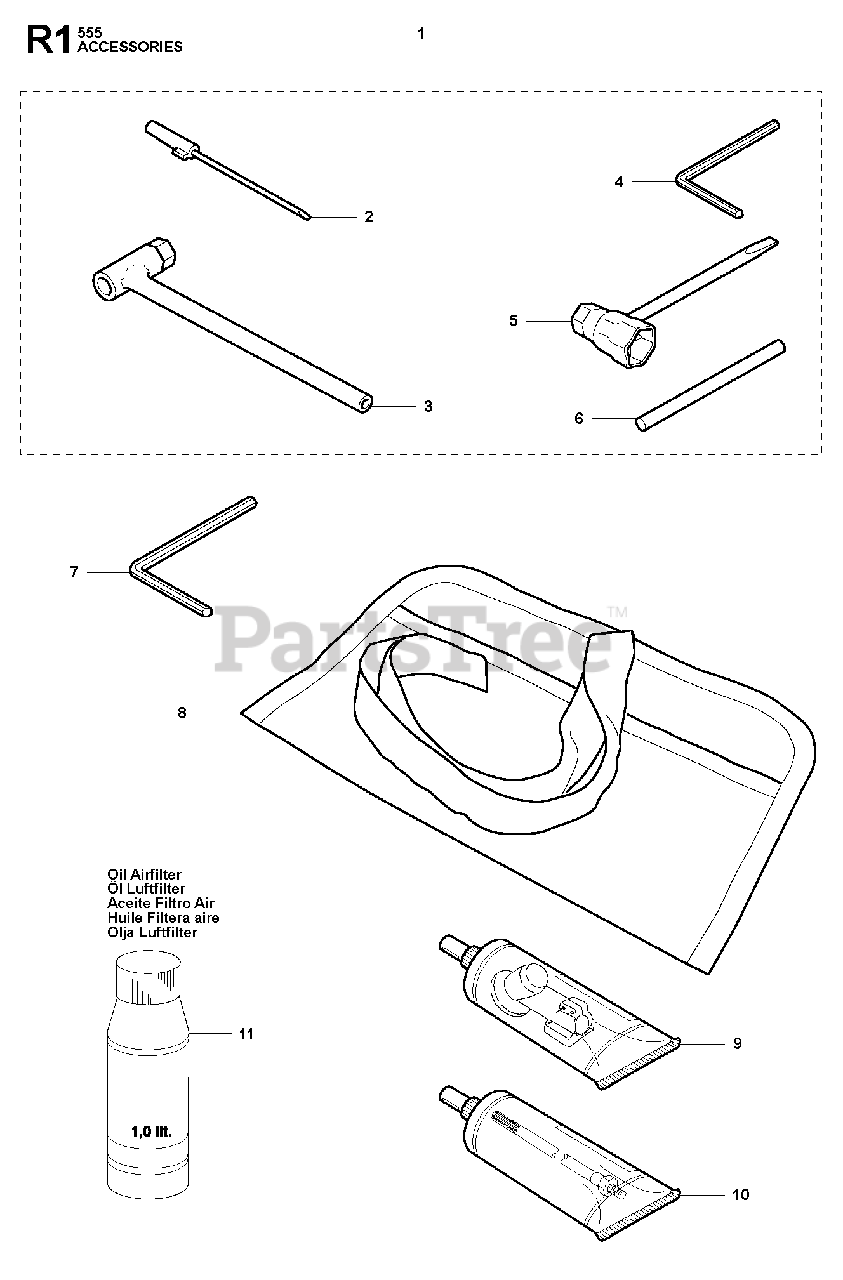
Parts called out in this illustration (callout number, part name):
1	RP ACCESSORY BAG
2	SCREWDRIVER
3	SCRENCH
4	L-KEY WRENCH
5	COMBI TOOL
6	LOCKING PIN
7	KEY
9	BEVEL GEAR GREASE
11	Air Filter Oil, HVA 1L Bottle
